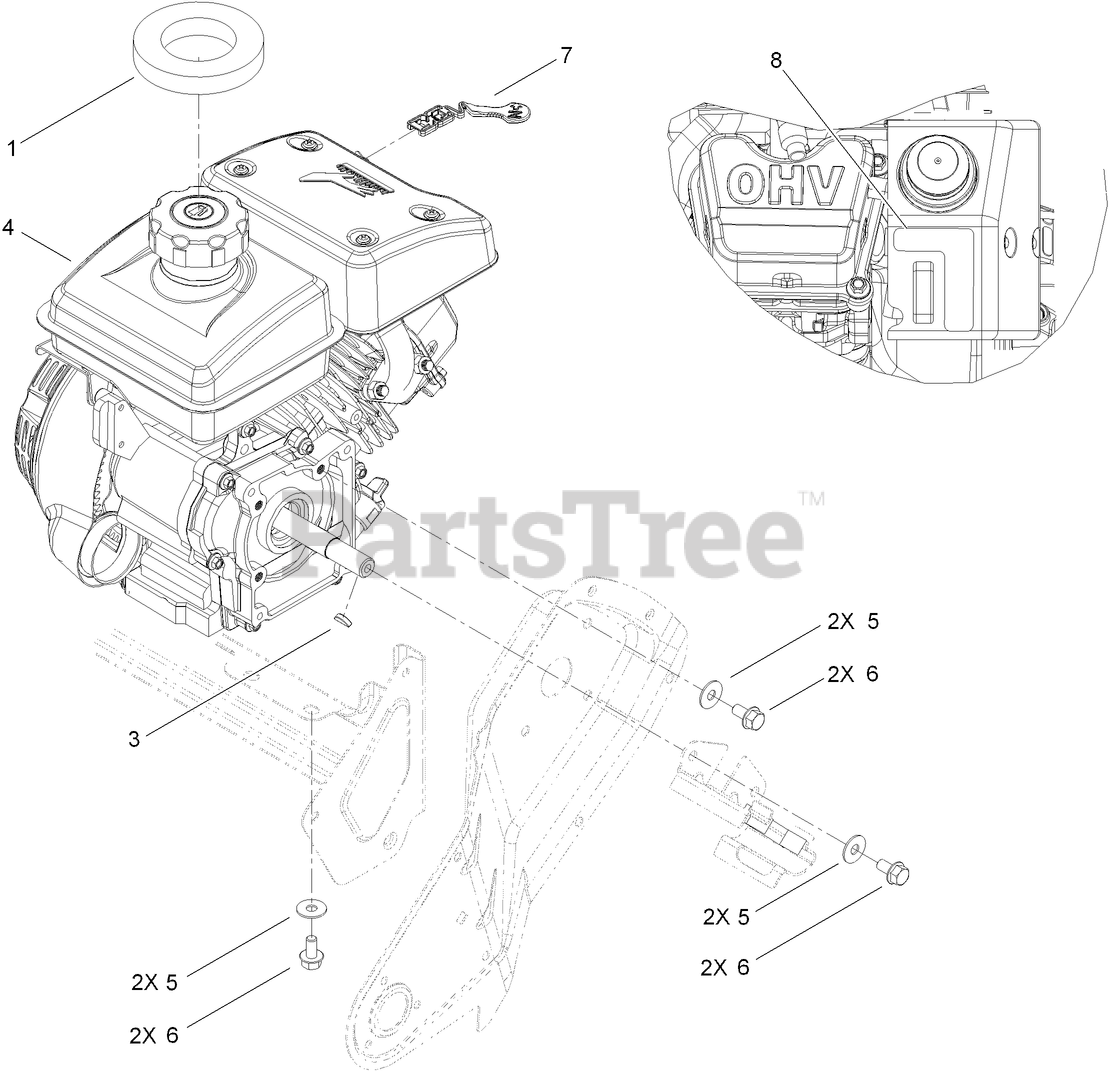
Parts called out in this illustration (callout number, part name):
1	SEAL-TANK
3	KEY-WOODRUFF
4	ENGINE-154FS-1
5	WASHER-BELLEVILLE
6	SCREW-HHF
7	LEVER-CHOKE
8	DECAL-CONTROL, ENGINE
